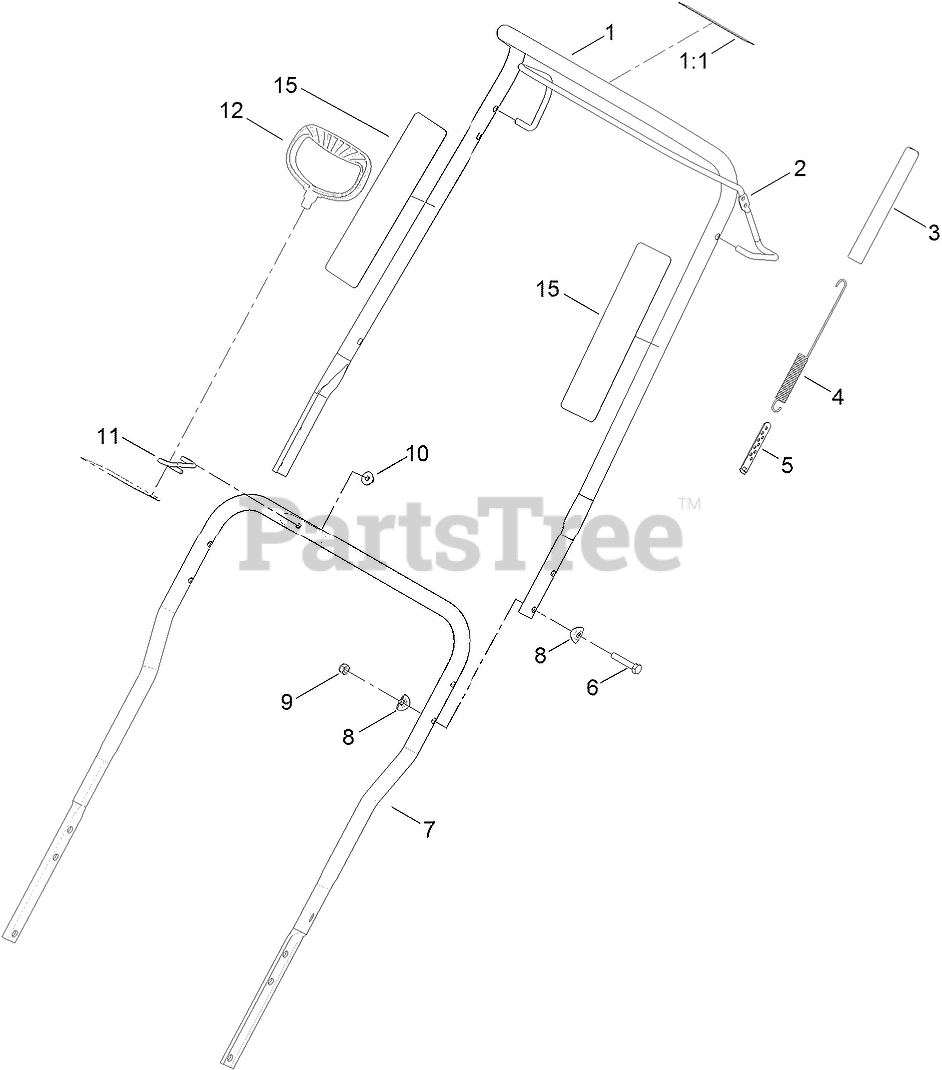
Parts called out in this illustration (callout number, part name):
1	UPPER HANDLE ASM
1:1	DECAL-DRIVE, ROTOR
2	BAIL-CONTROL
3	COVER-SPRING
4	SPRING-EXTENSION, CLUTCH
5	ADJUSTER-CABLE, CLUTCH
6	SCREW-HH
7	HANDLE-LOWER
8	WASHER
9	NUT-LOCK, NI
10	NUT-HEX FLG
11	GUIDE-ROPE
12	HANDLE-RECOIL
15	DECAL-TAPE, REFLECTIVE
